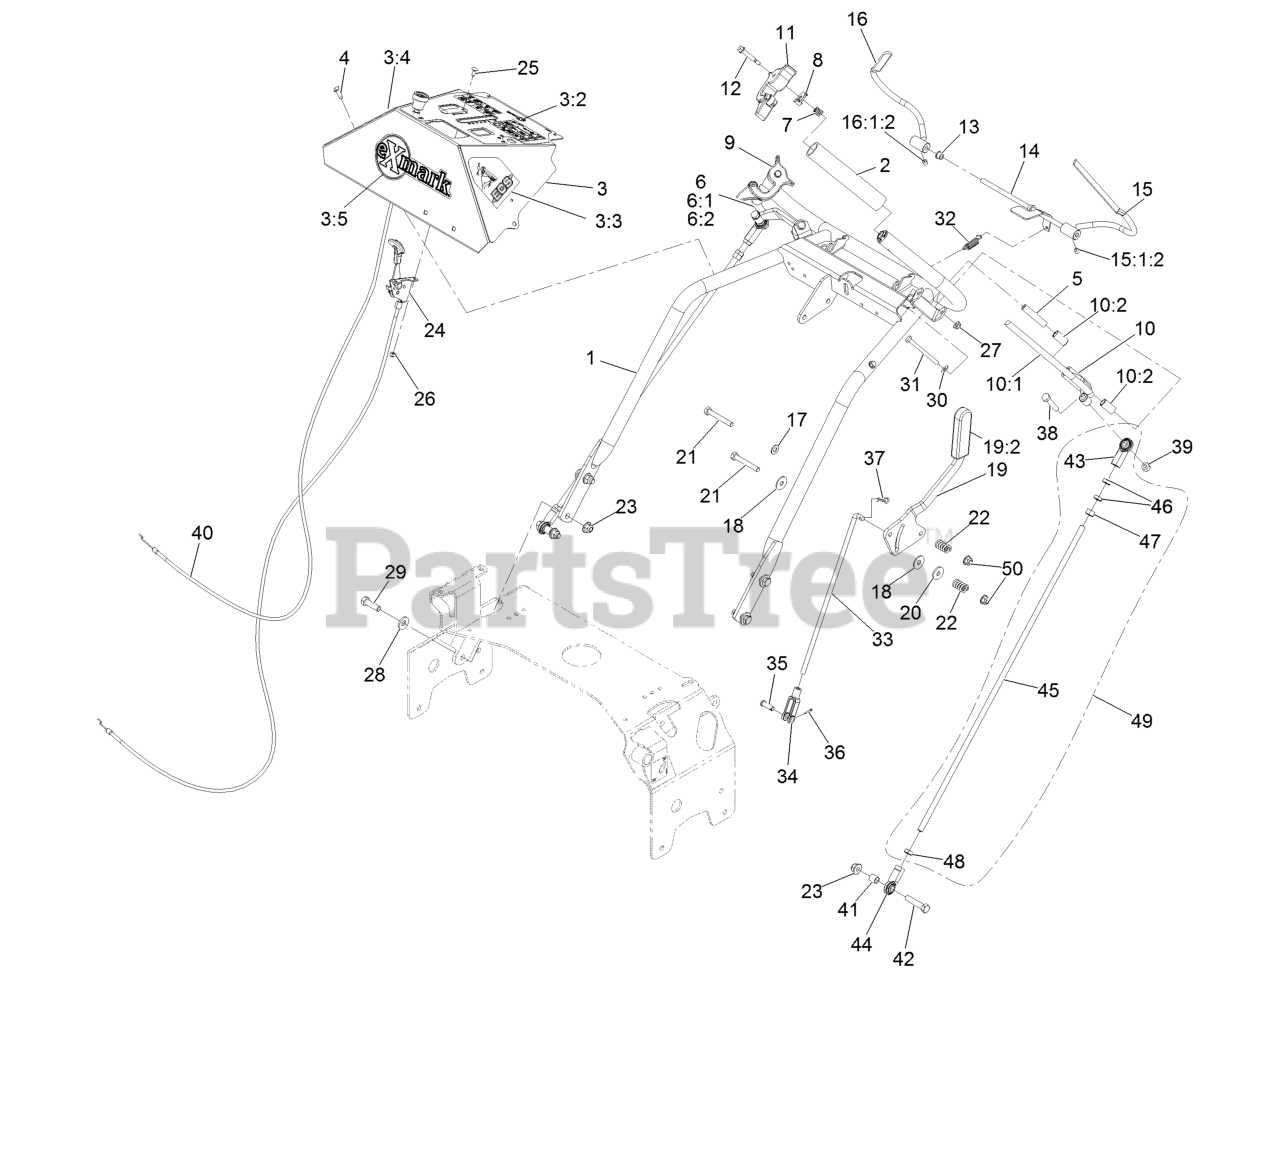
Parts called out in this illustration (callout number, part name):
1	Weld, Handle
2	Grip-Bar, Handle
3	ASM, Console W/ Decals
3:2	Decal-Console
3:3	Decal, Ecs Instruction LH
3:4	Decal, Ecs Instruction RH
3:5	Decal, Exmark Logo
4	Screw-HWH 1/4-20 X .62
5	Bushing-Lever, Drive
6	Asm, Drive Lever RH
6:1	Wld,RH Drive Lever
6:2	Bushing, Sleeve
7	Spring-Compression
8	Latch, Ecs
9	Thumb Latch Asm RH
10	Asm, Drive Lever LH
10:1	Wld,LH Drive Lever
10:2	Bushing, Sleeve
11	Thumb Latch Asm LH
12	Screw-Shoulder
13	Bushing-Nylon
14	Rod Weldment, OPC
15	Wld,LH OPC Lever
15:1:2	Setscrew-5/16-24 X 5/16
16	Wld,RH OPC Lever
16:1:2	Setscrew-5/16-24 X 5/16
17	Washer-5/16 SAE
18	Washer-Friction
19	Lever, Shift W/Grip
19:2	Grip-Handle, Steering
20	Washer-Friction Disc
21	Screw-HH 5/16-18 X 2 1/4
22	Spring-Compression
23	Nut-Nyloc 3/8-16 Flg
24	Control-Throttle
25	Bolt-Carriage #10-24 X 1/2
26	Nut-Nyloc #10-24
27	Nut-Nyloc 1/4-20 Flg
28	Washer-Spring Disc 3/8
29	Screw-HH 3/8-16 X 1 1/4
30	Washer-1/4 SAE
31	Screw-HH 1/4-20 X 2 3/4
32	Spring-Extension
33	Rod, Speed Control
34	Yoke-Adjustable
35	Pin-Clevis 5/16 X 1 49/64
36	Pin-Cotter 3/32 X 1/2
37	Hairpin-Cotter
38	Screw-HH 5/16-18 X 1 3/4
39	Nut-Nyloc 5/16-18
40	Cable, Choke
41	Spacer-Tube, Pump Link
42	Screw-HH 3/8-16 X 1 3/4
43	Balljoint
44	Joint-Ball End
45	Rod,Drive Lever
46	Nut-Jam 3/8-24
47	Nut-Hex 3/8-24
48	Nut-Jam 3/8-24 LH
49	Drive Link ASM
50	Nut-Nyloc 5/16-18 Flg
